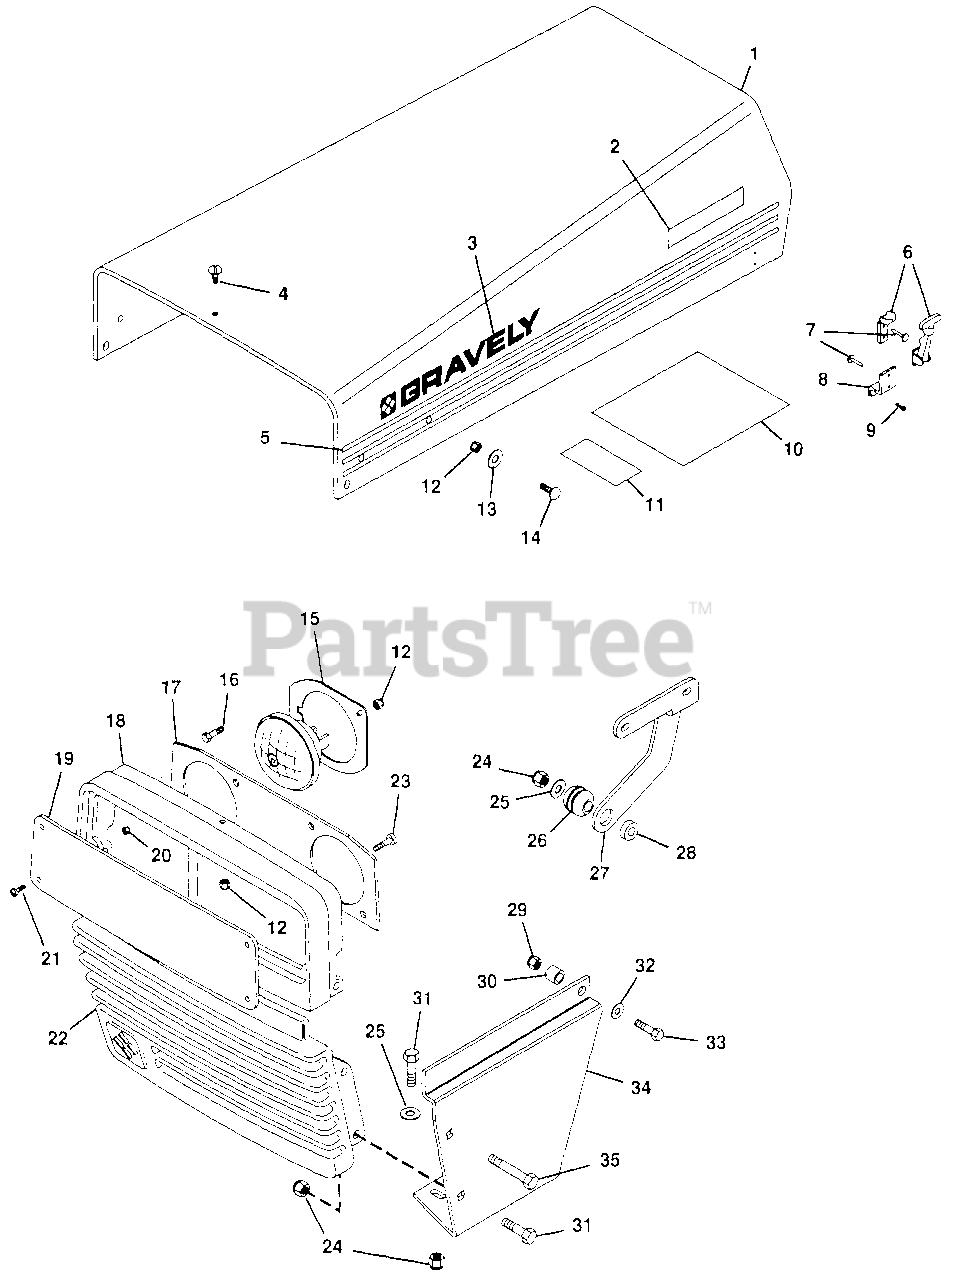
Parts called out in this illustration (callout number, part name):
1	HOOD, SILK SCREEN
2	DECAL, MODEL 14-G
2	DECAL, MODEL 16-G
2	DECAL, MODEL 18-G
2	DECAL, MODEL 20-G
3	DECAL, GRAVELY LOGO
4	SCREW, MACHINE 1/4-20 PHD
5	DECAL, SIDE STRIPE L.H. AND R.H.
6	LATCH, FLEXIBLE
7	RIVET, DOME HEAD
8	BRACKET, HOOD LATCH MOUNTING
9	SCREW, 8-18X.375 PHD CR
10	DECAL, MAINTENANCE
11	DECAL, ELECTRICAL SYSTEM WARNING
12	NUT, LOCK 1/4-20
13	WASHER, FLAT .281X.625X.065
14	BOLT, 1/4-20X.75 RD HD SQ NK
15	RING, HEADLIGHT RETAINER
16	BOLT, HEX 1/4-20X1.00
17	PANEL, HEADLIGHT REFLECTOR
18	BEZEL, HEADLIGHT
19	PANEL, HEADLIGHT LENSE
20	NUT, LOCK 10-24
21	SCREW, MACHINE 10-24X.75 PHD
22	CASTING, GRILLE
23	SCREW, 1/4-20X.50 SELF-TAPPING
24	NUT, LOCK 3/8-16
25	WASHER, FLAT .438X1.000X.083
26	GROMMET
27	HINGE, HOOD L.H.
27	HINGE, HOOD R.H.
28	SPACER
29	NUT, LOCK 5/16-18
30	BUSH., ST. .406X1.00X1.00 STL.
31	BOLT, HEX 3/8-16X1.00
32	WASHER, FLAT .344X.688X.065
33	BOLT, HEX 5/16-18X1.75
34	PANEL, SIDE L.H.
34	PANEL, SIDE R.H.
35	BOLT, HEX 3/8-16X2.00
